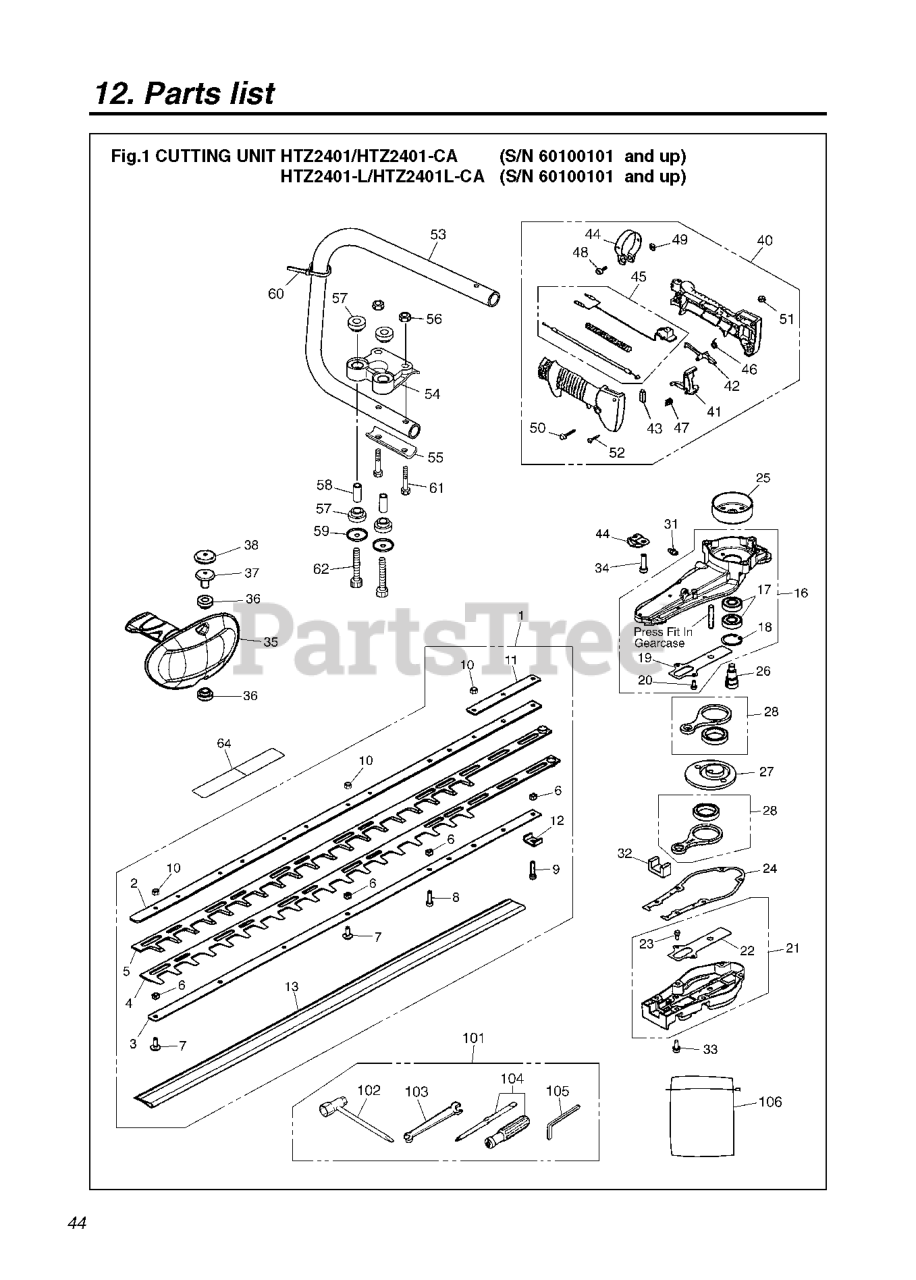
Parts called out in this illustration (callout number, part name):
1	BLADE ASSY
2	PLATE UPPER
3	PLATE LOWER
4	BLADE LOWER
5	BLADE UPPER
6	SPACER
7	SCREW
8	BOLT
13	COVER
16	GEARCASE COMPLETE UPPER
21	GEARCASE COMP. BOTTOM
26	GEAR DRIVE
27	GEAR DRIVE
28	ROD ASSY
40	LEVER ASSY
42	LEVER
45	CABLE COMP
46	SPRING
50	SCREW
51	NUT
52	SCREW
57	ABSORBER
101	TOOL-SET
